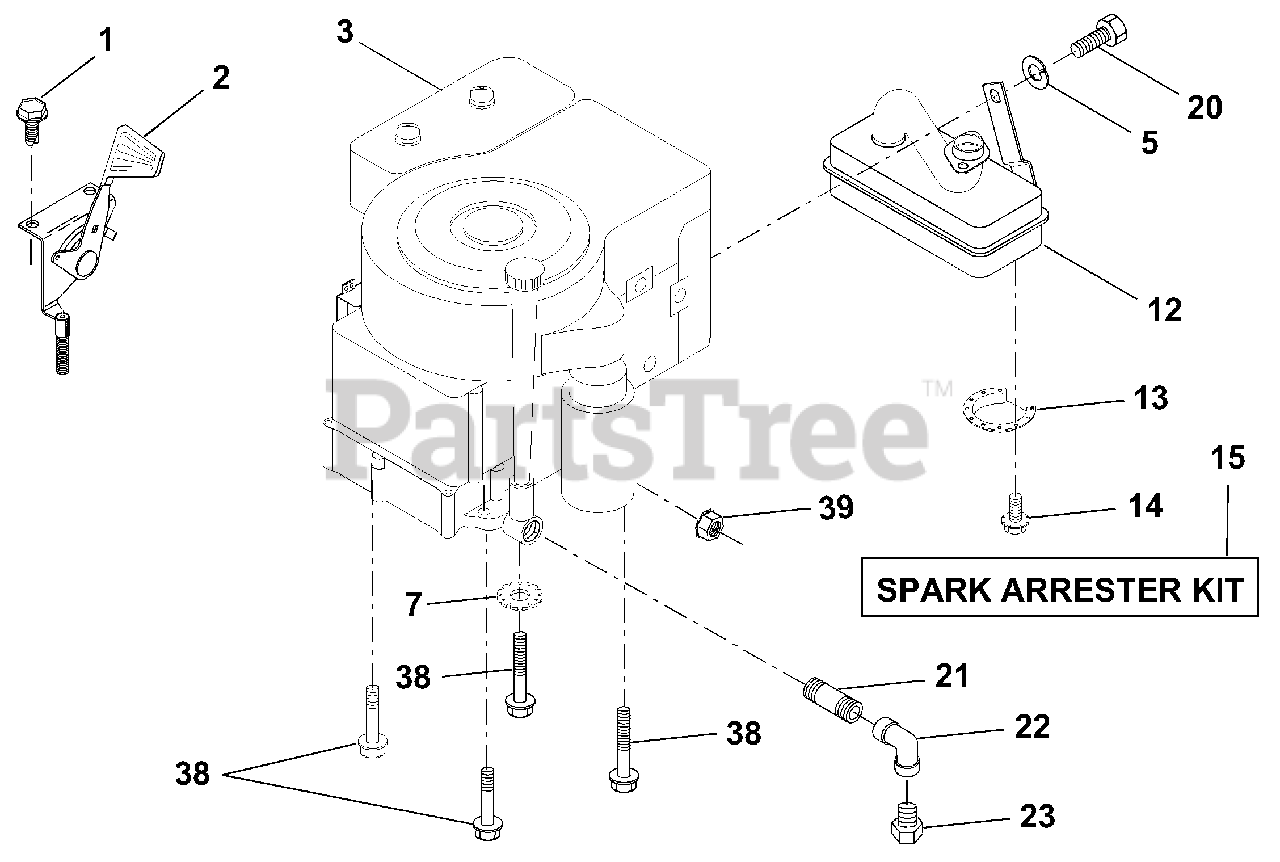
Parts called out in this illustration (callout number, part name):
1	Screw, Hex Head, Thread Cutting 1/4-20 x 1/2
2	Control, Throttle
3	Engine, Kohler, 12.5 HP
5	Washer, Lock, Hvy Hlcl Spring 5/16
7	Washer Lock Ext. Tooth 3/8
13	Deflector Muffler
14	Screw Spiderloc Hex Hd # 8 x 1/2 AB
15	Arrester, Spark
20	Bolt, Hex, Fin. 5/16 - 18 x 1/2
21	Nipple Pipe
22	Elbow
23	Oil Drain Plug
38	Bolt Hex
39	Nut, Keps, Hex 1/4-20
